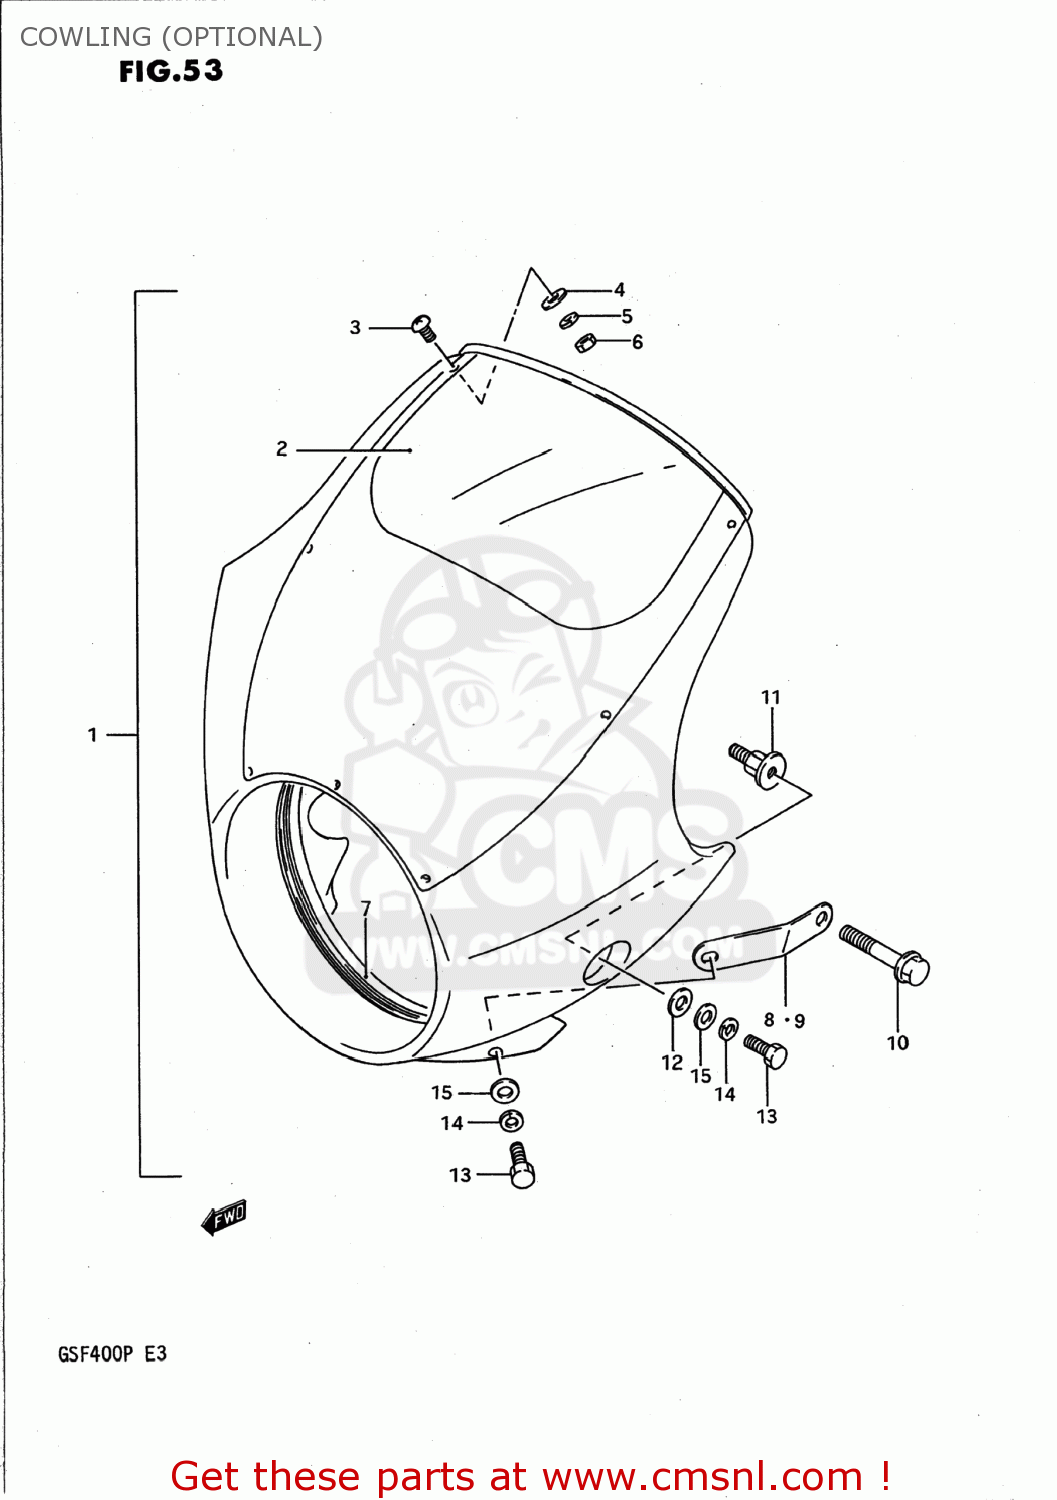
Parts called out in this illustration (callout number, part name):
1	COVER SET,COWLING,UPPER
2	SCREEN
3	SCREW
4	WASHER
5	LOCK WASHER
6	NUT
7	MOLDING,COWLING
8	BRACE,COWLING,RIGHT
9	BRACE,COWLING,LEFT
10	BOLT, RH
11	BOLT,COWLING HEADLAMP
12	WASHER
13	BOLT
14	WASHER,LOCK
15	WASHER
